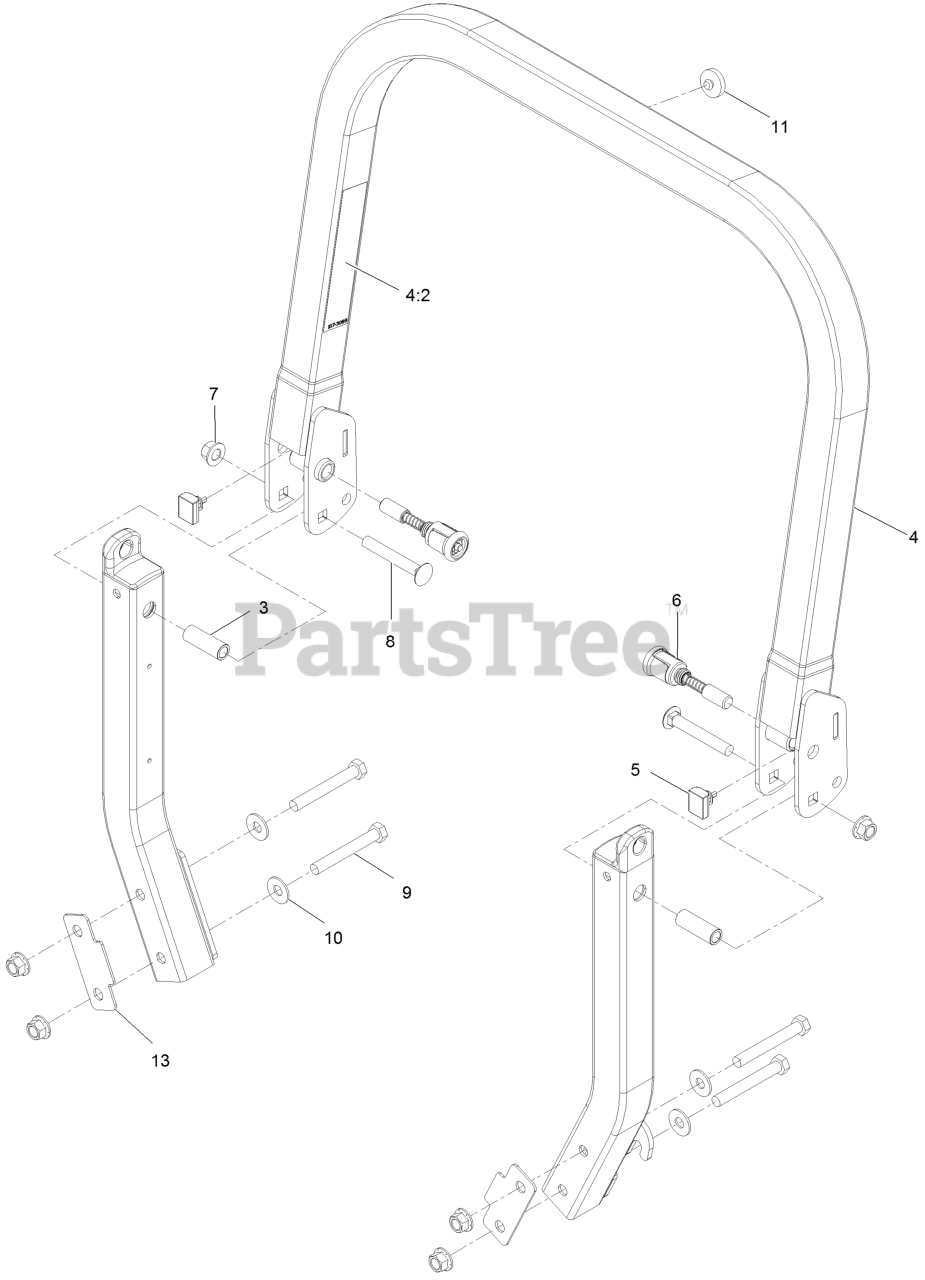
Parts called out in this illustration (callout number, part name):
4	UPPER ROPS ASM
4:2	DECAL-WARNING
5	BUMPER-ROPS
6	PIN-SPRING
7	Nut-Lock 1/2-13
8	SCREW-CARR
9	WASHER-LOCK
10	WASHER-SPRING
11	BUMPER-PUSH-IN, RUBBER
